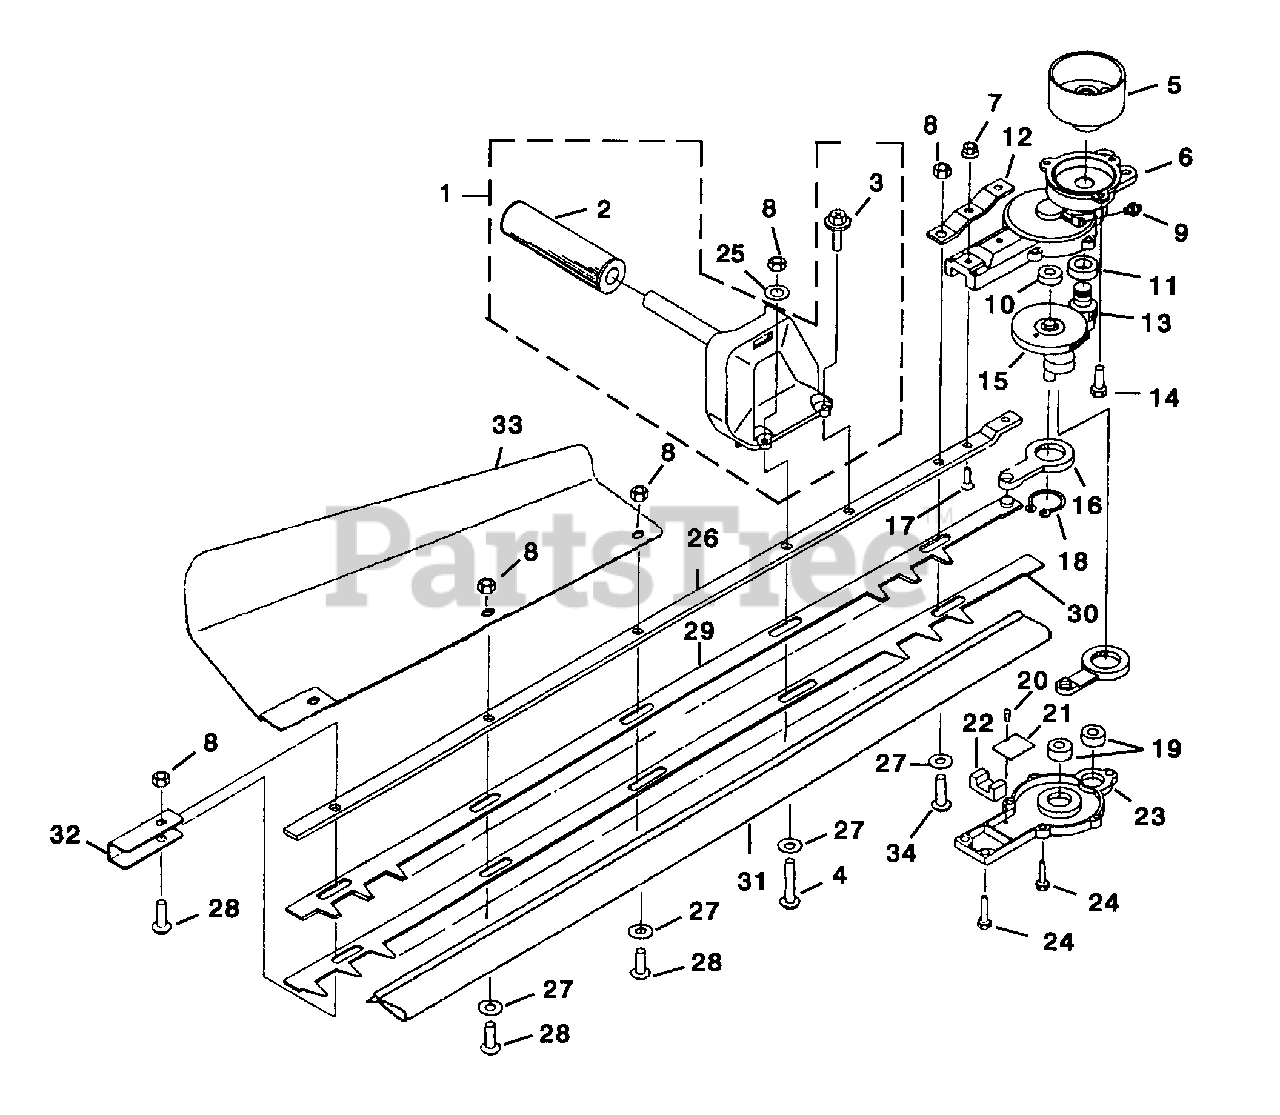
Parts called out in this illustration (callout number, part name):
1	FRONT HANDLE ASSEMBLY
3	SCREW (M5 x 20 SW & PW)
4	SCREW (L-29)
5	DRUM-Clutch
6	CASE-Upper
7	NUT-Flange (MS)
8	NUT (M6)
9	NIPPLE-Grease (M6)
12	PLATE-Reinforcing
13	GEAR-Pinion
14	BOLT (M6 x 15 W SW)
15	GEAR CRANK ASSEMBLY
17	SCREW (MS x 20)
18	SNAP RING
20	SCREW (M3 x 5)
21	PLATE-Rod Slide
23	LOWER CASE
24	BOLT (M5 x 16 W SW)
26	GUIDE PLATE
27	WASHER-Blade Side
28	SCREW (L-22)
29	BLADE-Upper
30	BLADE-Lower
31	BLADE COVER
32	BLADE-End Reinforcer
33	RECEIVER PLATE
34	SCREW (L-22)
